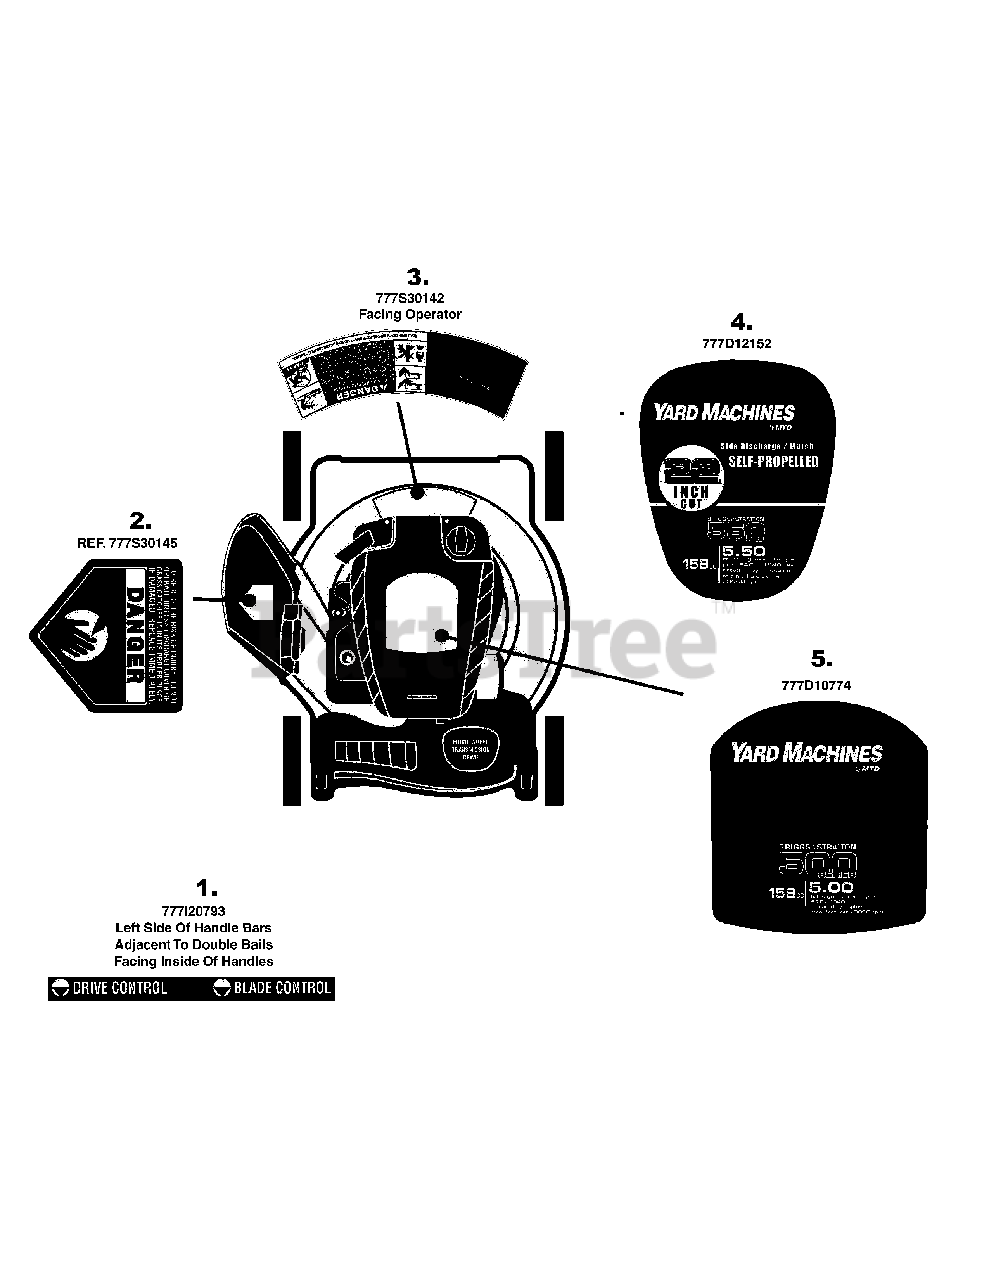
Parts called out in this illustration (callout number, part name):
1	LABEL-HANDLE
2	LABEL
3	LABEL-DANGER CURVE
4	LABEL-MOWER SHROUD YARD MACH 22"
5	LABEL-MOWER SHROUD YARD MACH 22"
